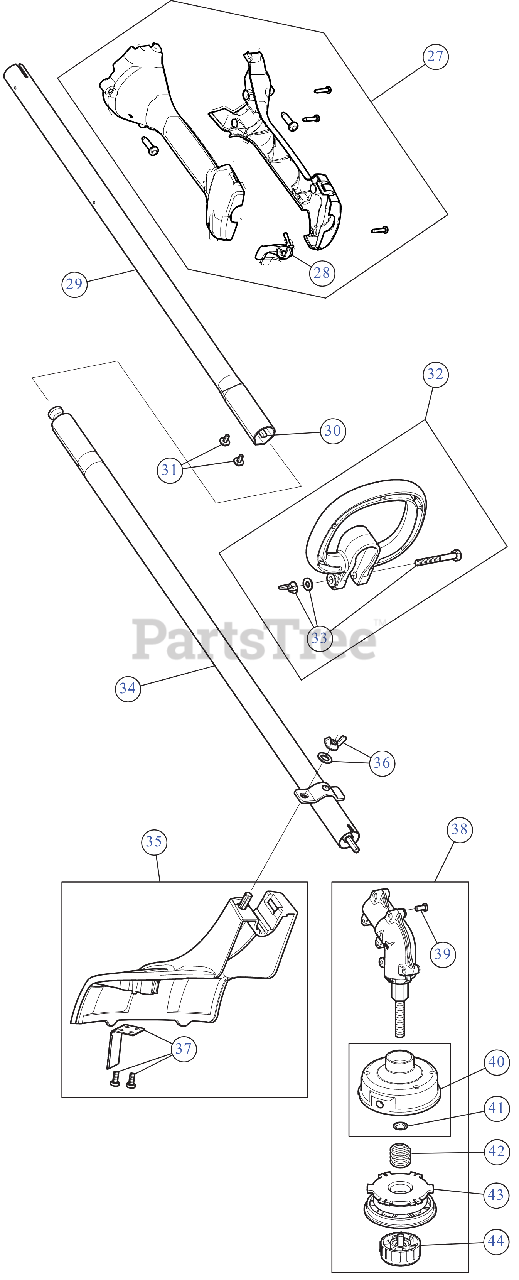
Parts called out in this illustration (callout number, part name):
27	THROTTLE GRIP ASSEMBLY
28	THROTTLE TRIGGER
29	UPPER BOOM ASSEMBLY
30	UPPER BOOM ASSEMBLY
31	SCREW 8-32X3/8
32	HANDLE
33	HANDLE HWD
34	LOWER BOOM ASSEMBLY
35	GUARD & BLADE ASSEMBLY
36	BLADE GUARD MOUNTING HARDWARE
37	BLADE ASSEMBLY W/HDW
38	GEARBOX ASSEMBLY
39	SCREW 8-32X.437
40	REEL:OTR W/RET
41	RETAINER .625 OD 2
42	SPRING-SPOOL
43	REEL-INNER SPOOL
44	BUMP HEAD KNOB ASSEMBLY
